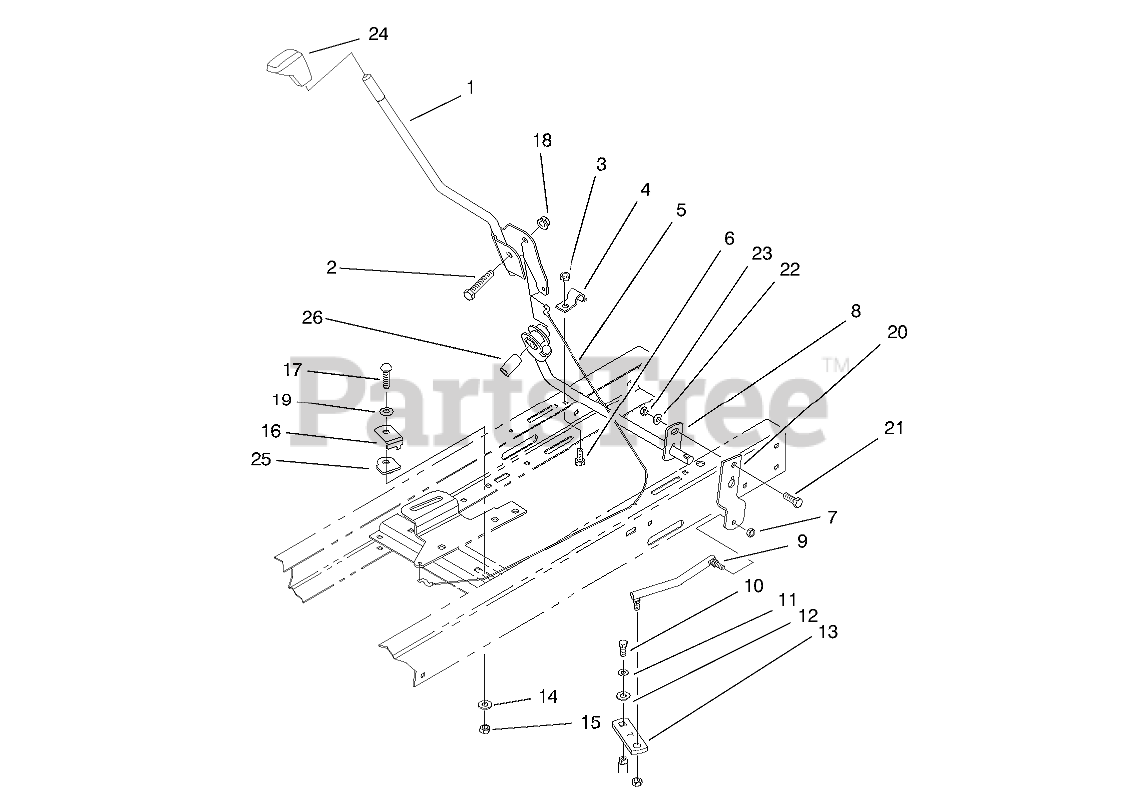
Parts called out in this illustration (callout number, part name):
1	LEVER-SHIFT ASM
2	SCREW-HH
3	NUT-LOCK, NI
4	CLAMP-PIVOT, SHIFT
5	CABLE-CLUTCH
6	SCREW-HH
7	NUT-LOCK
8	SHIFT PIVOT ASM
9	LINK-SHIFT
10	SCREW-HH
11	WASHER-LOCK
12	SPACER
13	LEVER-SHIFT
14	WASHER-PLAIN
15	NUT-LOCK, NI
16	KEEPER-CABLE
17	SCREW-CARR
18	NUT-LOCK, NI
19	WASHER-FLAT
20	LEVER-PIVOT, SHIFT
21	SCREW-HH
22	WASHER-PLAIN
23	NUT-LOCK, NI
24	KNOB-SHIFT
25	GUIDE-CABLE
26	BUSHING-SHIFT, LEVER
